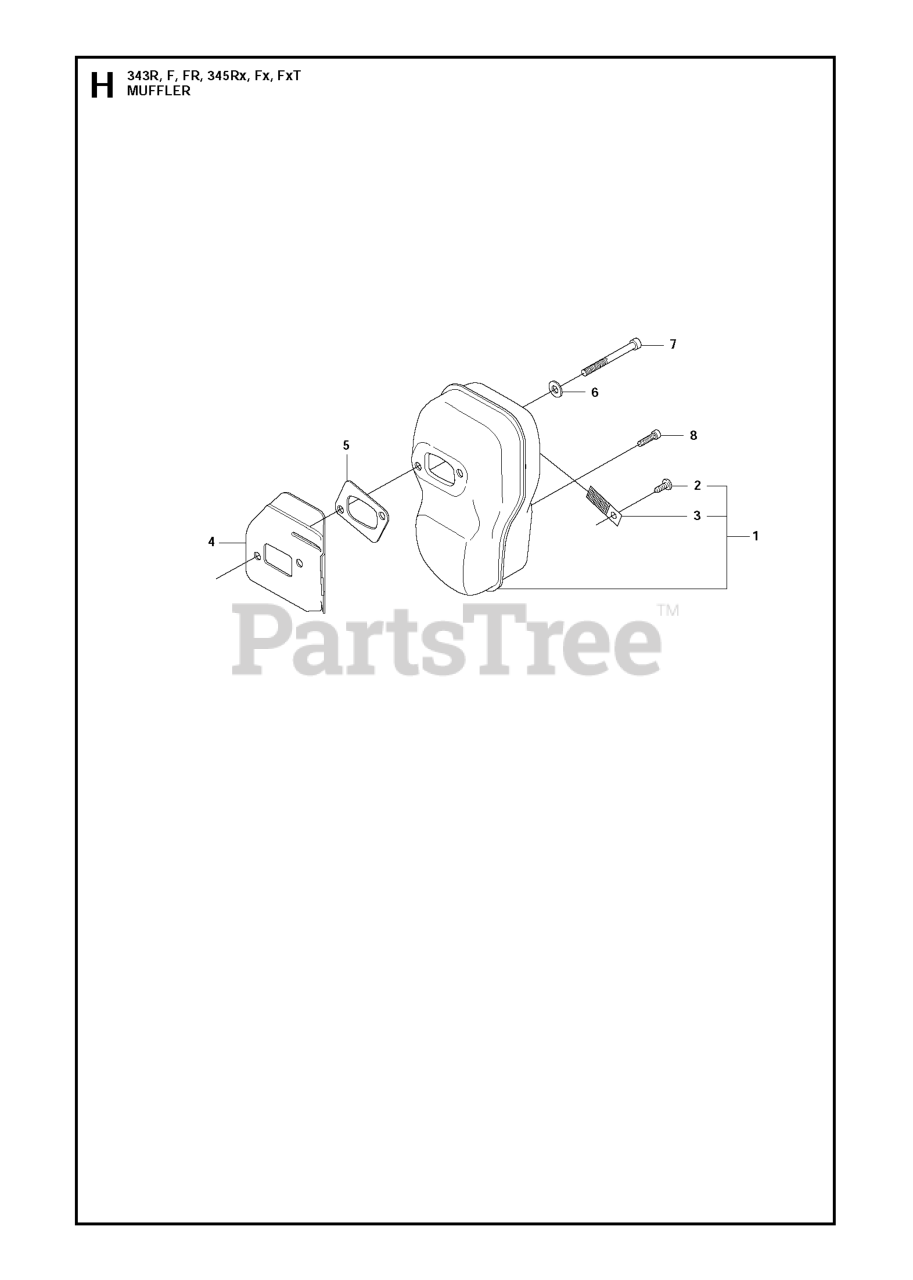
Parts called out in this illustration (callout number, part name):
1	MUFFLER
6	DOUBLE WASHER
8	SCREW IHSCFM
